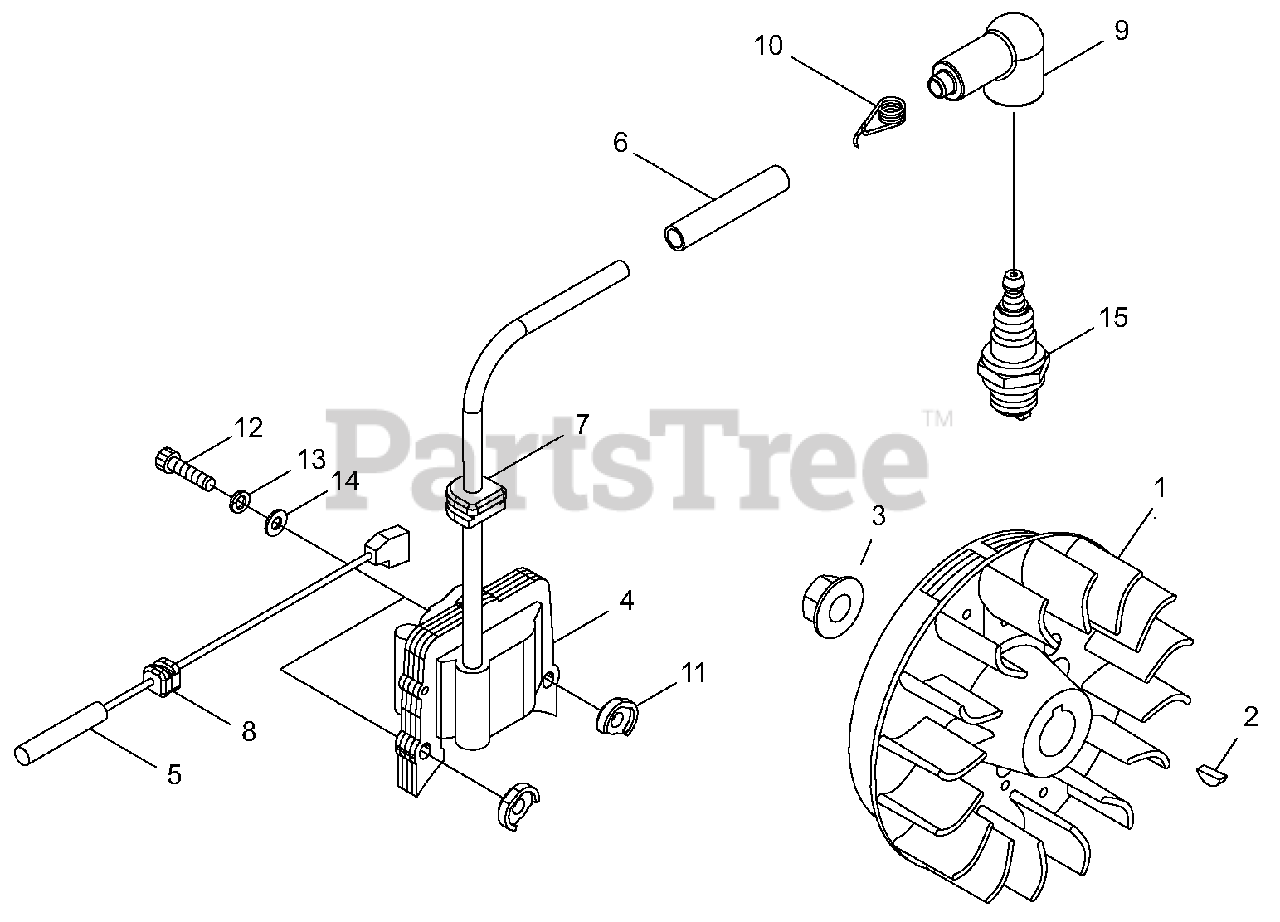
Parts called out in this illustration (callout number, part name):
1	FLYWHEEL
2	KEY - 3X10
3	NUT - FLANGE
4	COIL, IGNITION
5	LEAD - IGNITION
6	TUBE
7	GROMMET
8	GROMMET
9	CAP, SPARK PLUG
10	TERMINAL, SPARK PLUG CAP
11	INSULATOR
12	BOLT - 4X24
13	LOCKWASHER - 4
14	WASHER
15	SPARK PLUG -- CJ-8
